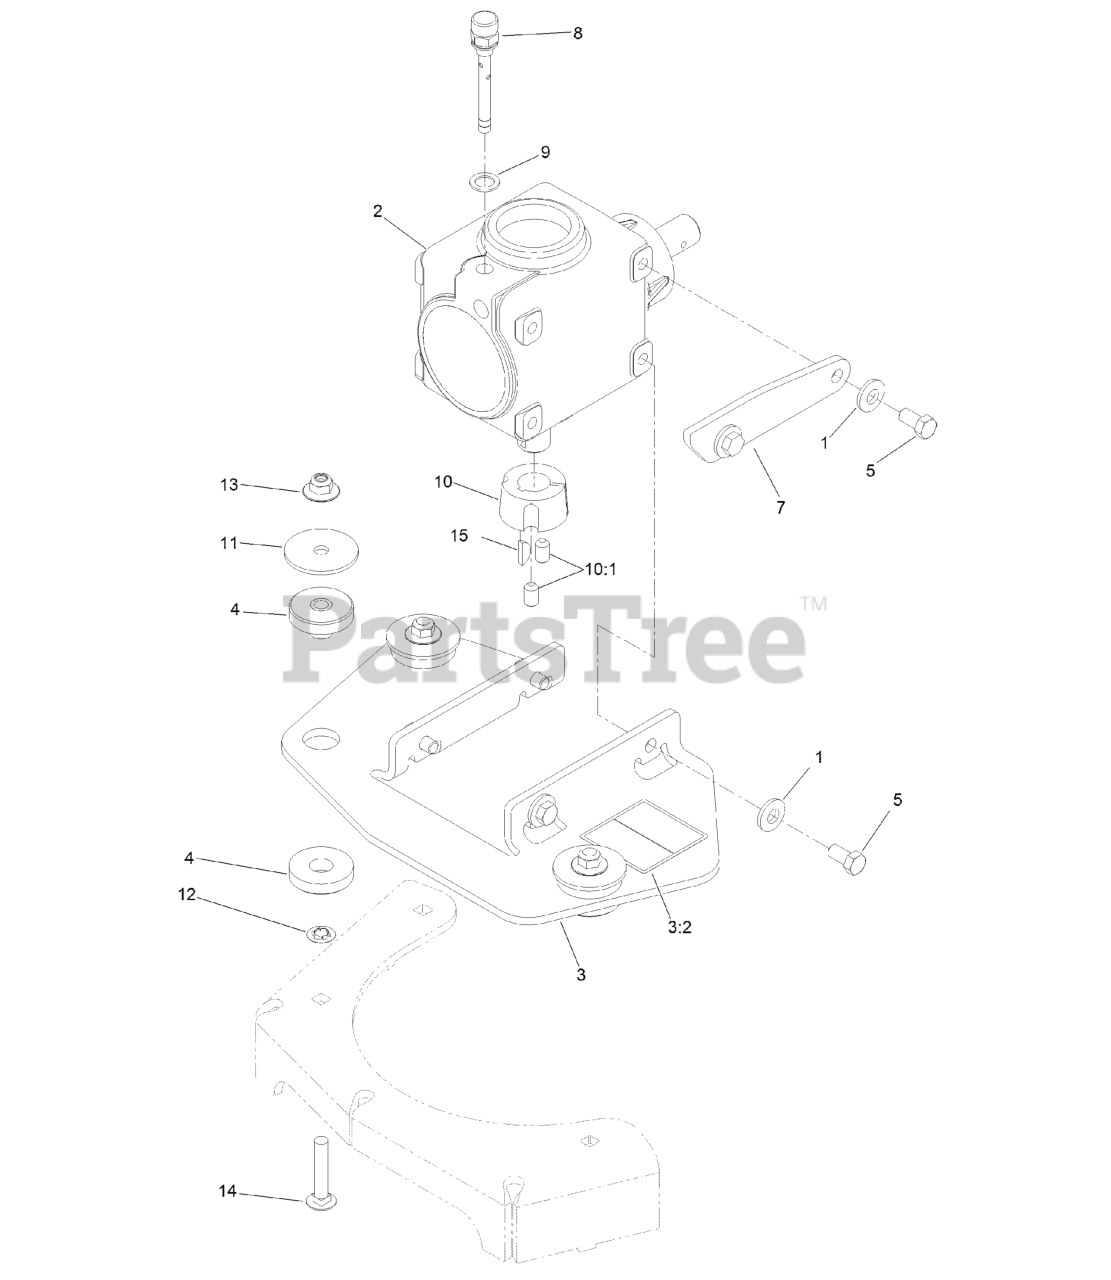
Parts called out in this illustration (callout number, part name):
1	WASHER-BELLEVILLE
2	GEARBOX ASM
3	MOUNT-GEARBOX
3:2	DECAL-HAZARD, ENTANGLEMENT
4	MOUNT-ISO
5	SCREW-HH
7	STOP-GEARBOX
8	PLUG-BREATHER
10	BUSHING-TAPERLOCK
10:1	SCREW-SET
11	WASHER-FLAT
12	NUT-PUSH
13	Nut-Nyloc 3/8-16 Flg
14	SCREW-CARR
15	KEY-WOODRUFF
